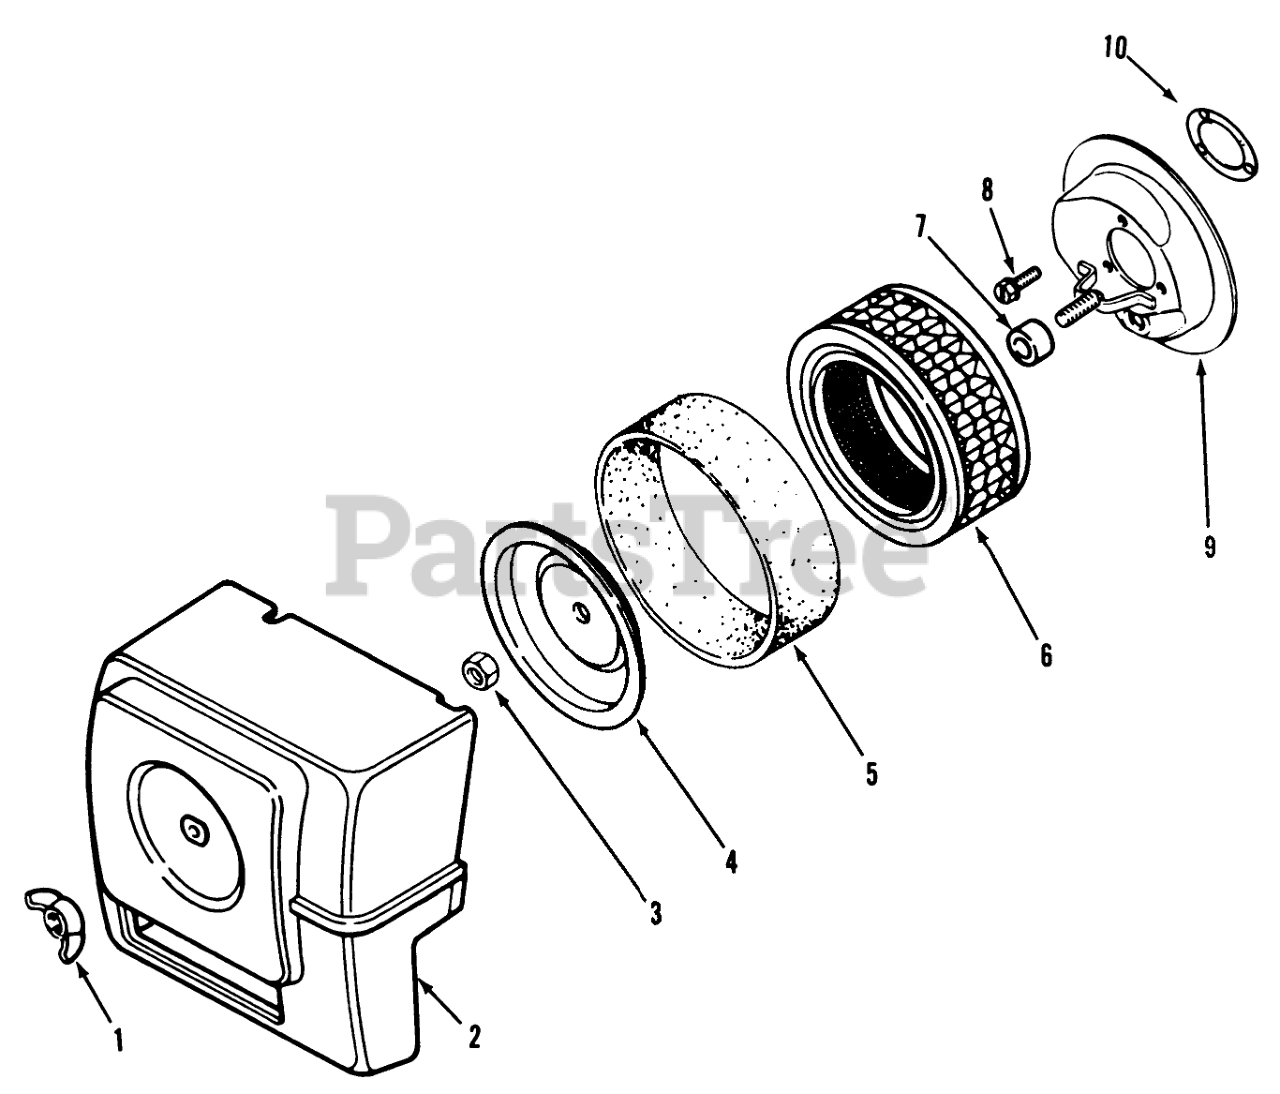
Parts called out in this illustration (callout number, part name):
1	Nut-Wing
2	Cover
4	Air Cleaner Element Cover
5	Element-Precleaner
6	Element
8	Screw
9	Base-AirCleaner
10	Gasket
